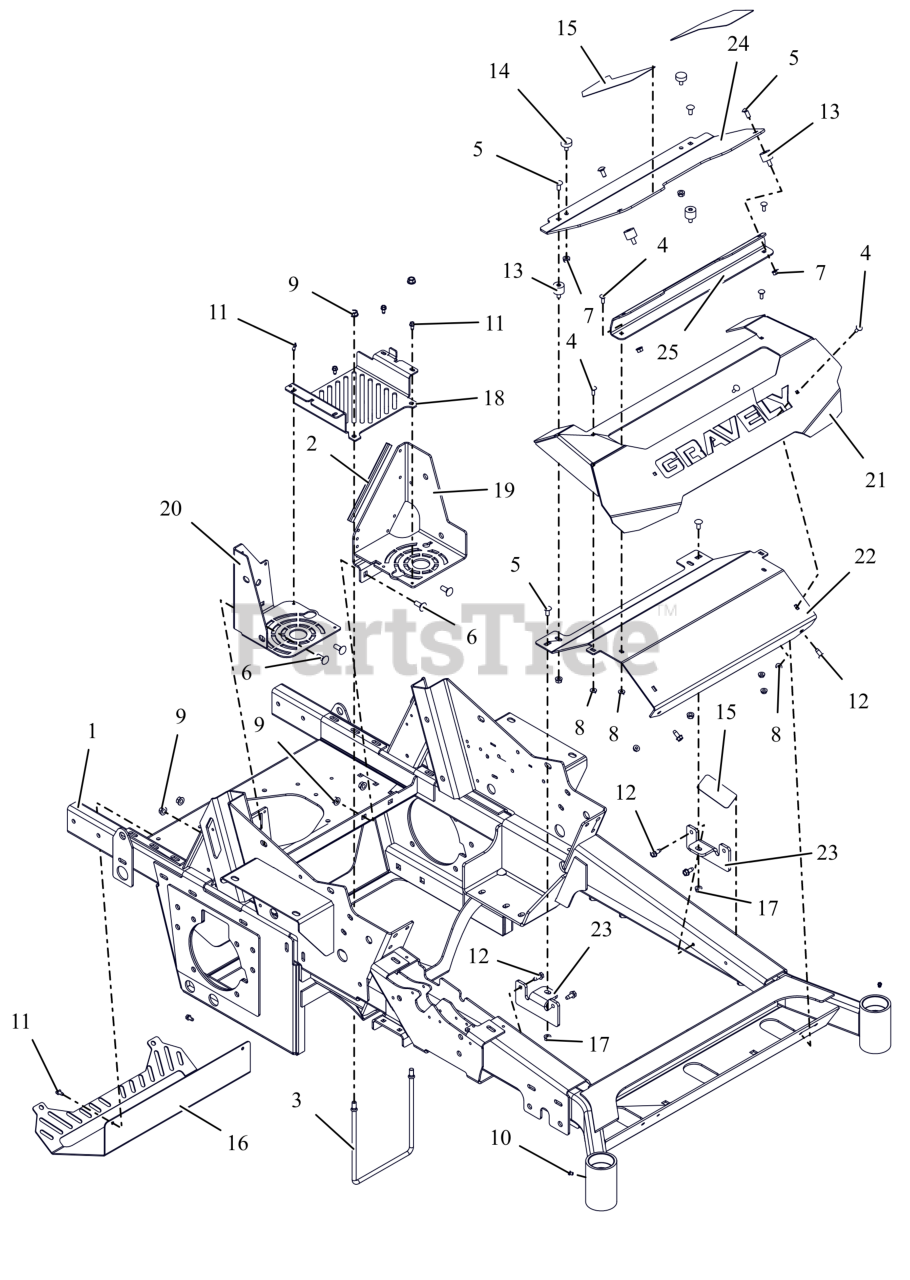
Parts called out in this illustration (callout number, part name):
1	WLDMT, 48", 52", 60" FRAME (RED)
2	STRIP, COWL
3	ROD, BRAKE MTG
4	BLT, RHSN .25-20X.750 G5 ZCC
5	BLT, RHSSN.31-18X.750 G5 ZCC
6	BLT, RHSN .38-16X1.00 G5 ZCC
7	NUT,SPNLK-FLG .31-18 G5 ZCC
8	NUT-LK-CTR-FLG .25-20 ZC120
9	NUT-LK-CTR-FLG .375-16 GF ZCC
10	FTG, .25-28 FLUSH MNT GREASE
11	SCR-TAP .25-20X.50 HWH ZCC
12	SCR,TAP .312-18X.75 HWH TR ZCC
13	BUMPER,STUD MNTD W/FEMALE INSR
14	BUMPER, RUBBER
15	KIT, PT300-600 ANTI-SKID Tape
16	GUARD, MUFFLER (BLACK)
17	NUT,LK-CTR-FLG .31-18 GF ZCC
18	TRAY- BATTERY
19	GUSSET-LH BATTERY TRY/ROPS-RED
20	GUSSET- FAN GUARD/ROPS - RED
21	BMPR-PT300-500 FRT FTRST/ -RED
22	BRKT-FRT BUMPER MTG/BACKER-BLK
23	BRKT- FOOTREST MTG
24	FOOTREST, PT300-500 (RED)
25	BRKT, FOOTREST SUPPORT (BLK)
